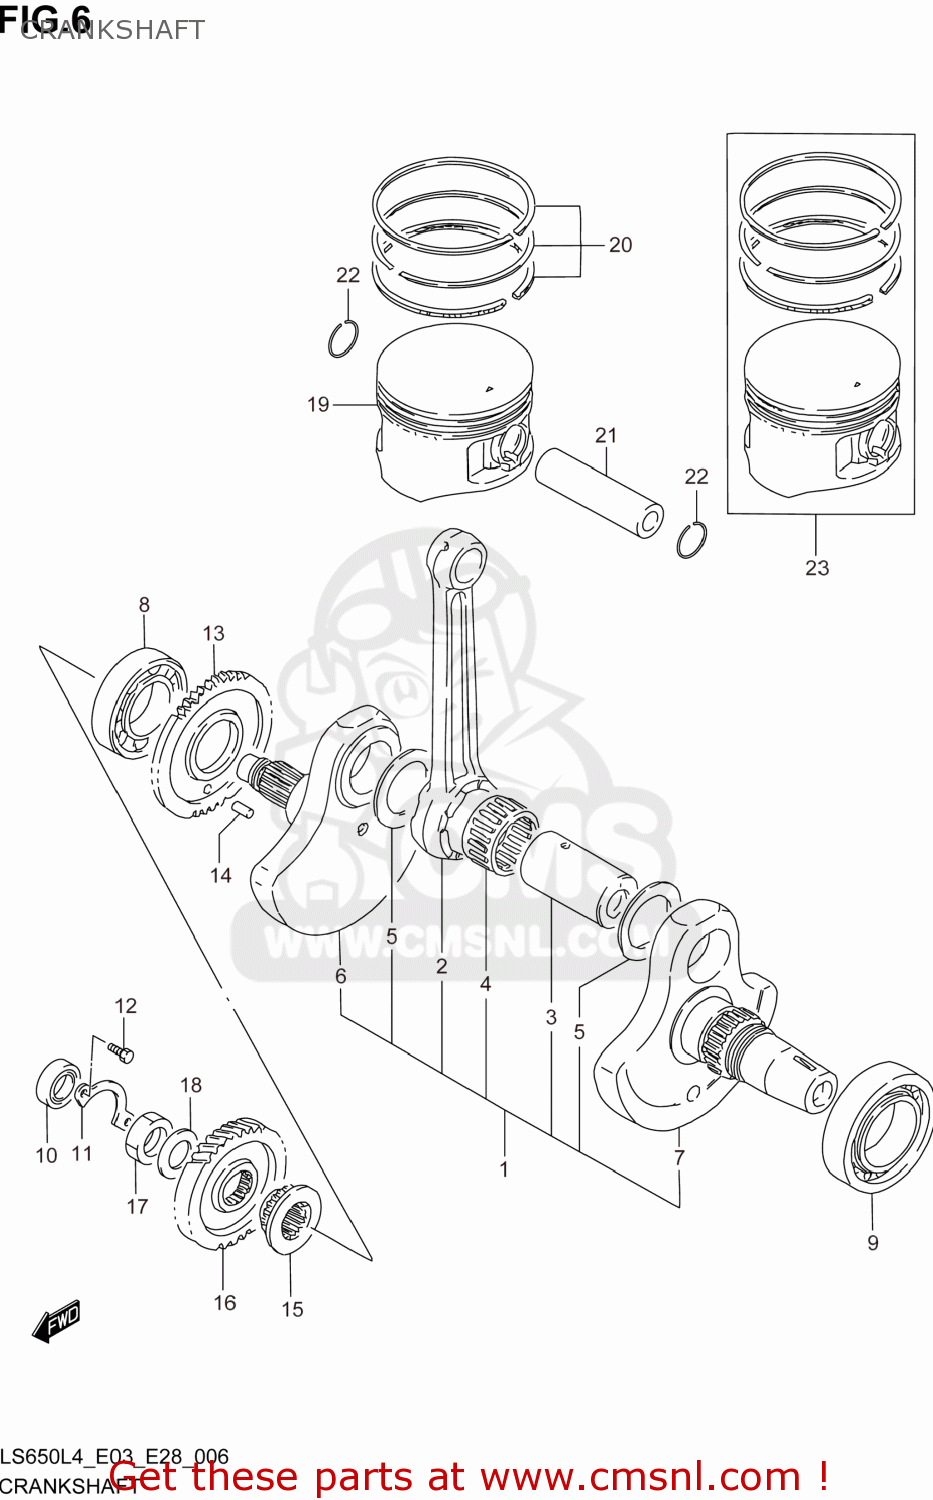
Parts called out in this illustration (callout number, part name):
1	CRANKSHAFT ASSY
2	ROD,CONNECTING
3	PIN,CRANK
4	BEARING(37X47X25)
5	WASHER(37X55X1)
6	CRANKSHAFT,R
7	CRANKSHAFT,L
8	BEARING(35X72X17)
9	BEARING(40X80X18)
10	SEAL,OIL(16X30X6)
11	RETAINER,CRANKSHAFT OIL SEAL,R
12	BOLT
13	GEAR,CRANK BALANCER DRIVE
14	PIN
15	SPROCKET,CAM CHAIN DRIVE
16	GEAR,PRIMARY DRIVE
17	NUT
18	WASHER
19	PISTON
20	RING SET,PISTON
21	PIN,PISTON
22	CIRCLIP
23	PISTON SET(OS:0.5)
